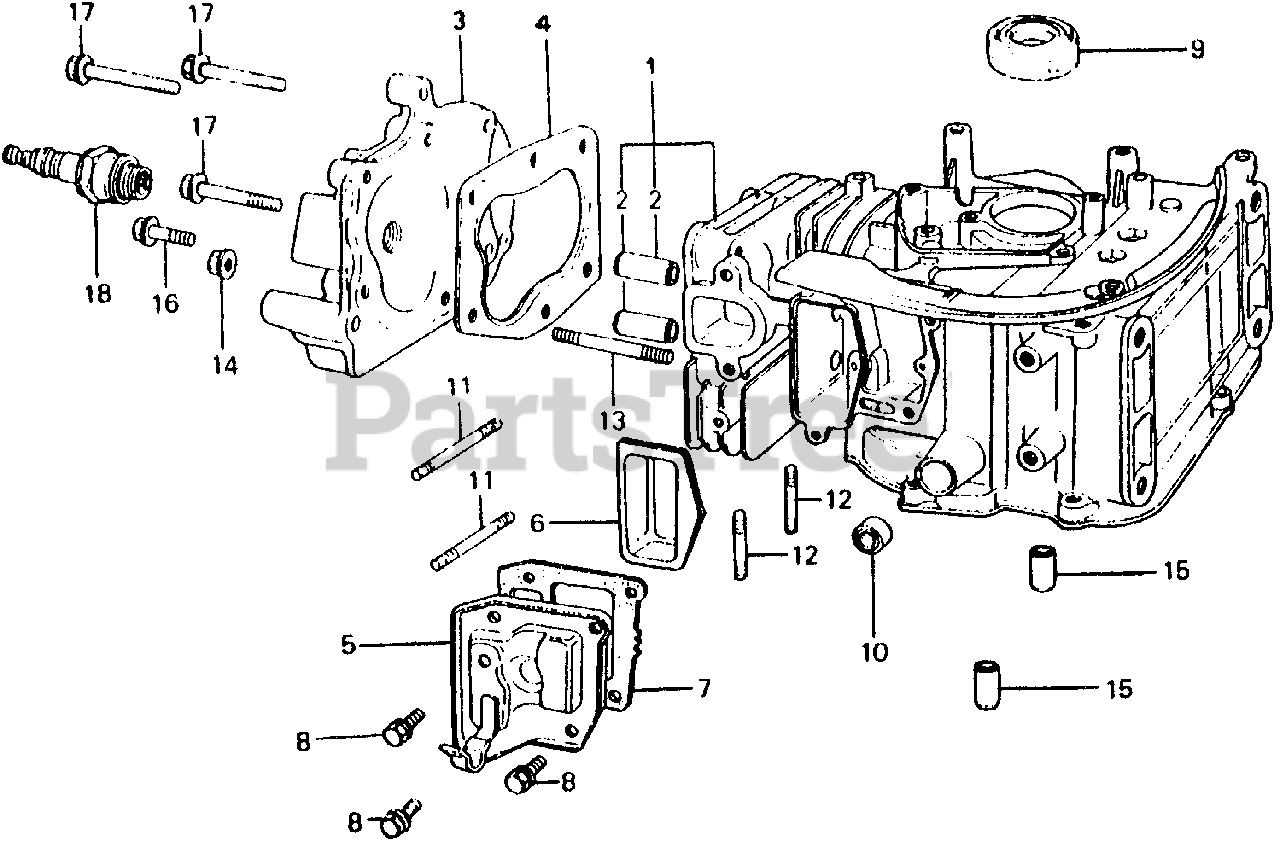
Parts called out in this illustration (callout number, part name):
2	GUIDE, VALVE (OS)
2	GUIDE, VALVE
3	CYLINDER HEAD (NOT AVAILABLE)
4	GASKET, CYLINDER HEAD
5	COVER, TAPPET (NOT AVAILABLE)
6	SEPARATOR (INNER)
6	SEPARATOR (INNER) (NOT AVAILABLE)
7	GASKET, TAPPET COVER (NOT AVAILABLE)
8	BOLT, FLANGE (5X10)
9	OIL SEAL (17X30X6) (NOK)
11	BOLT, STUD (5X40) (NOT AVAILABLE)
12	BOLT, STUD (6X28)
13	BOLT, STUD (6X45) (SOURCE: VINTAGE PARTS INC.)
14	NUT, FLANGE (6MM)
15	PIN A, DOWEL (8X14)
16	BOLT, FLANGE (6X12)
17	BOLT, FLANGE (6X35)
18	SPARK PLUG (BMR4A) (NGK)
18	SPARK PLUG (W14MR-U) (DENSO)
